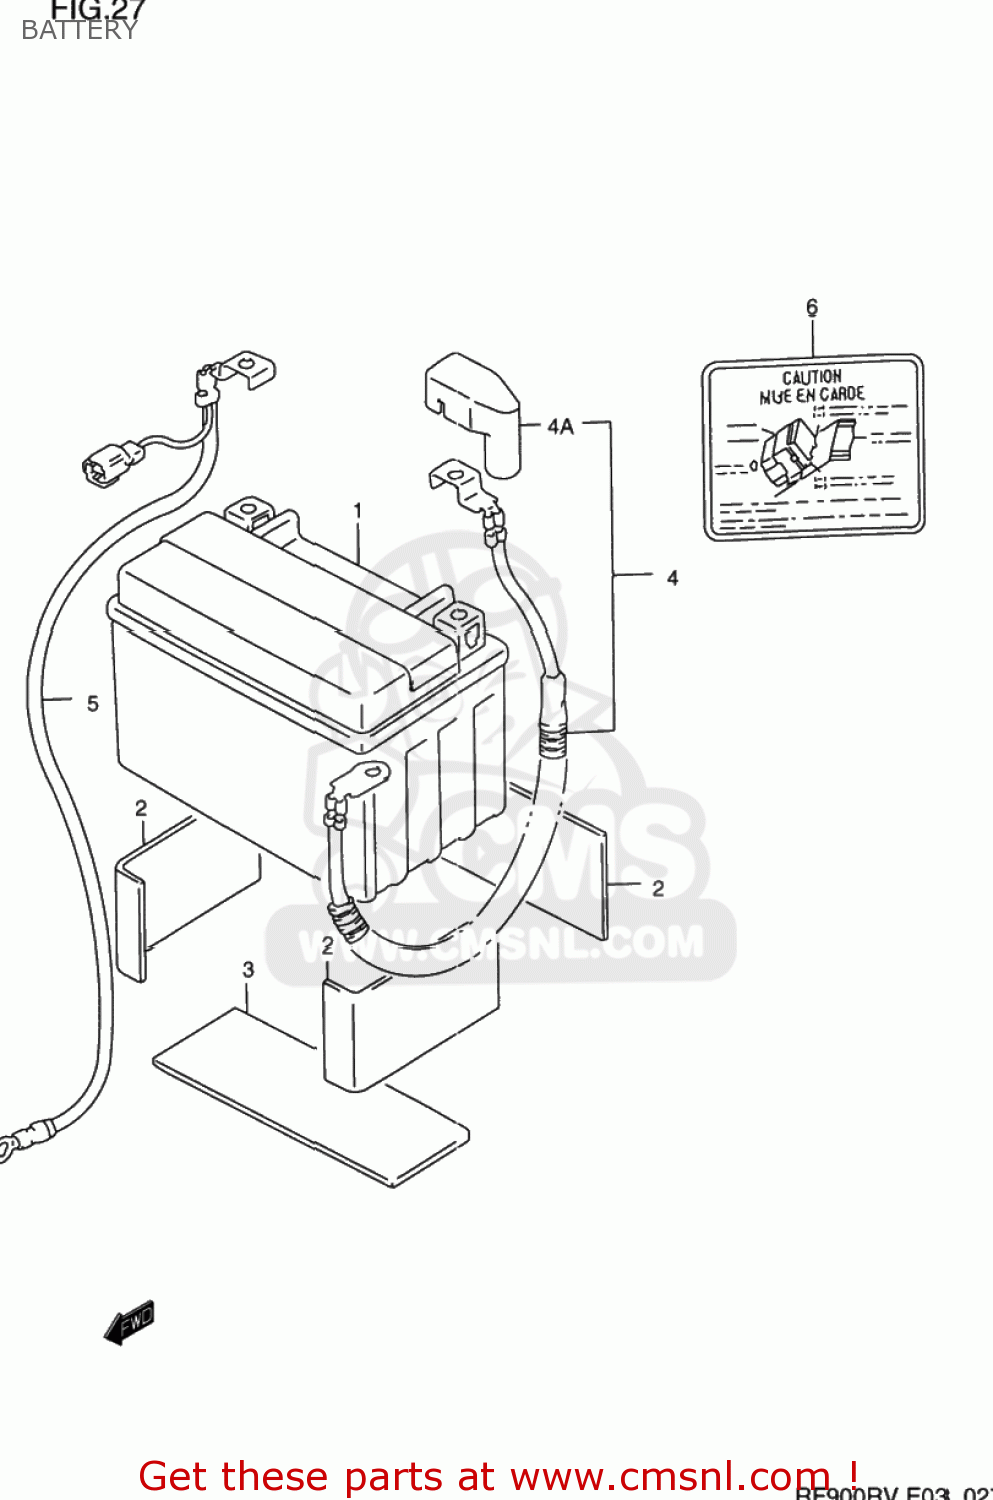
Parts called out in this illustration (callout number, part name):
1	BATTERY ASSEMBLY (12V) YTX
2	PROTECTOR(170X95X3.0)
3	PROTECTOR,BATTERY
4	WIRE,BATTERY PLUS LEAD
4A	CAP,BATTERY PLUS
5	WIRE,BATTERY MINUS
6	PLATE,BATTERY CAUTION
